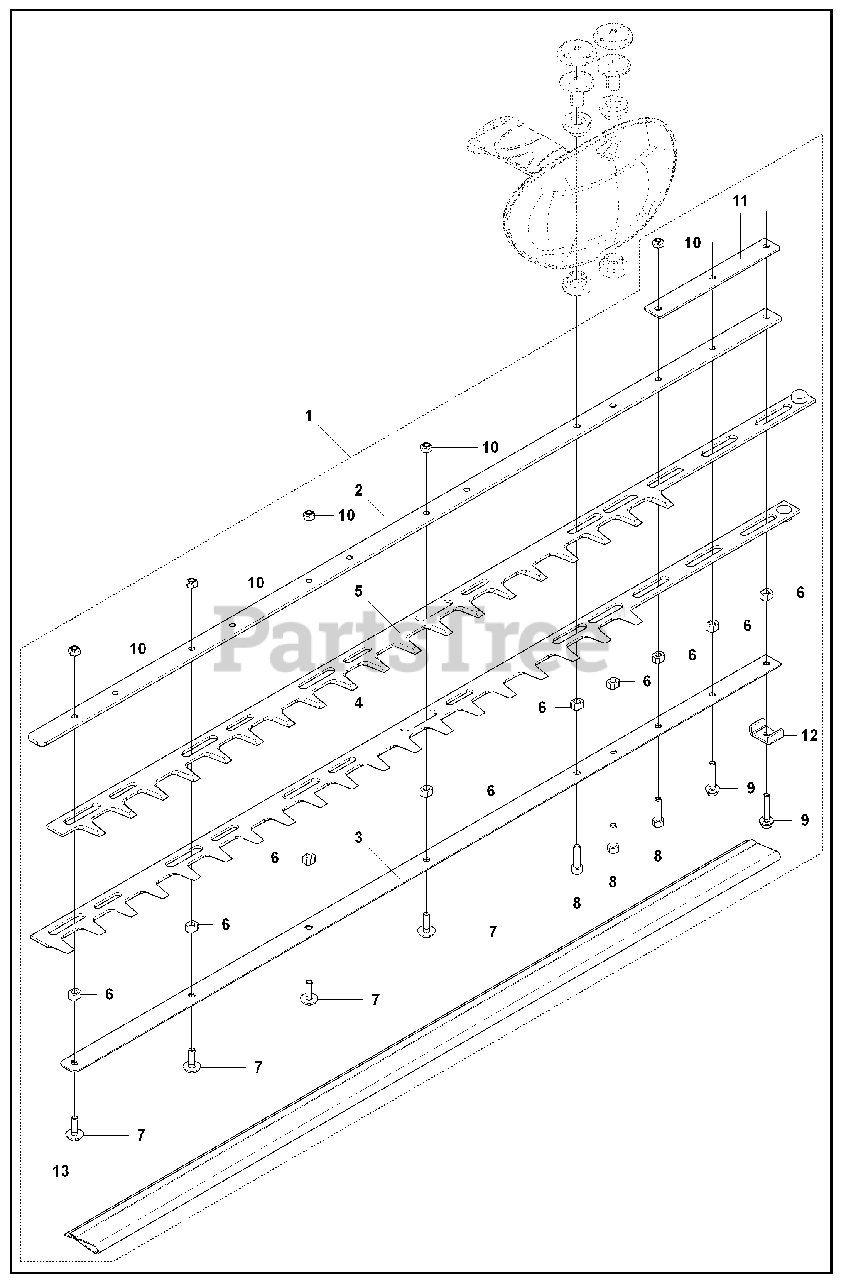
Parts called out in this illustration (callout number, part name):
1	BLADE ASSY
2	PLATE, upper
3	PLATE, lower
4	BLADE, lower
5	BLADE, upper
